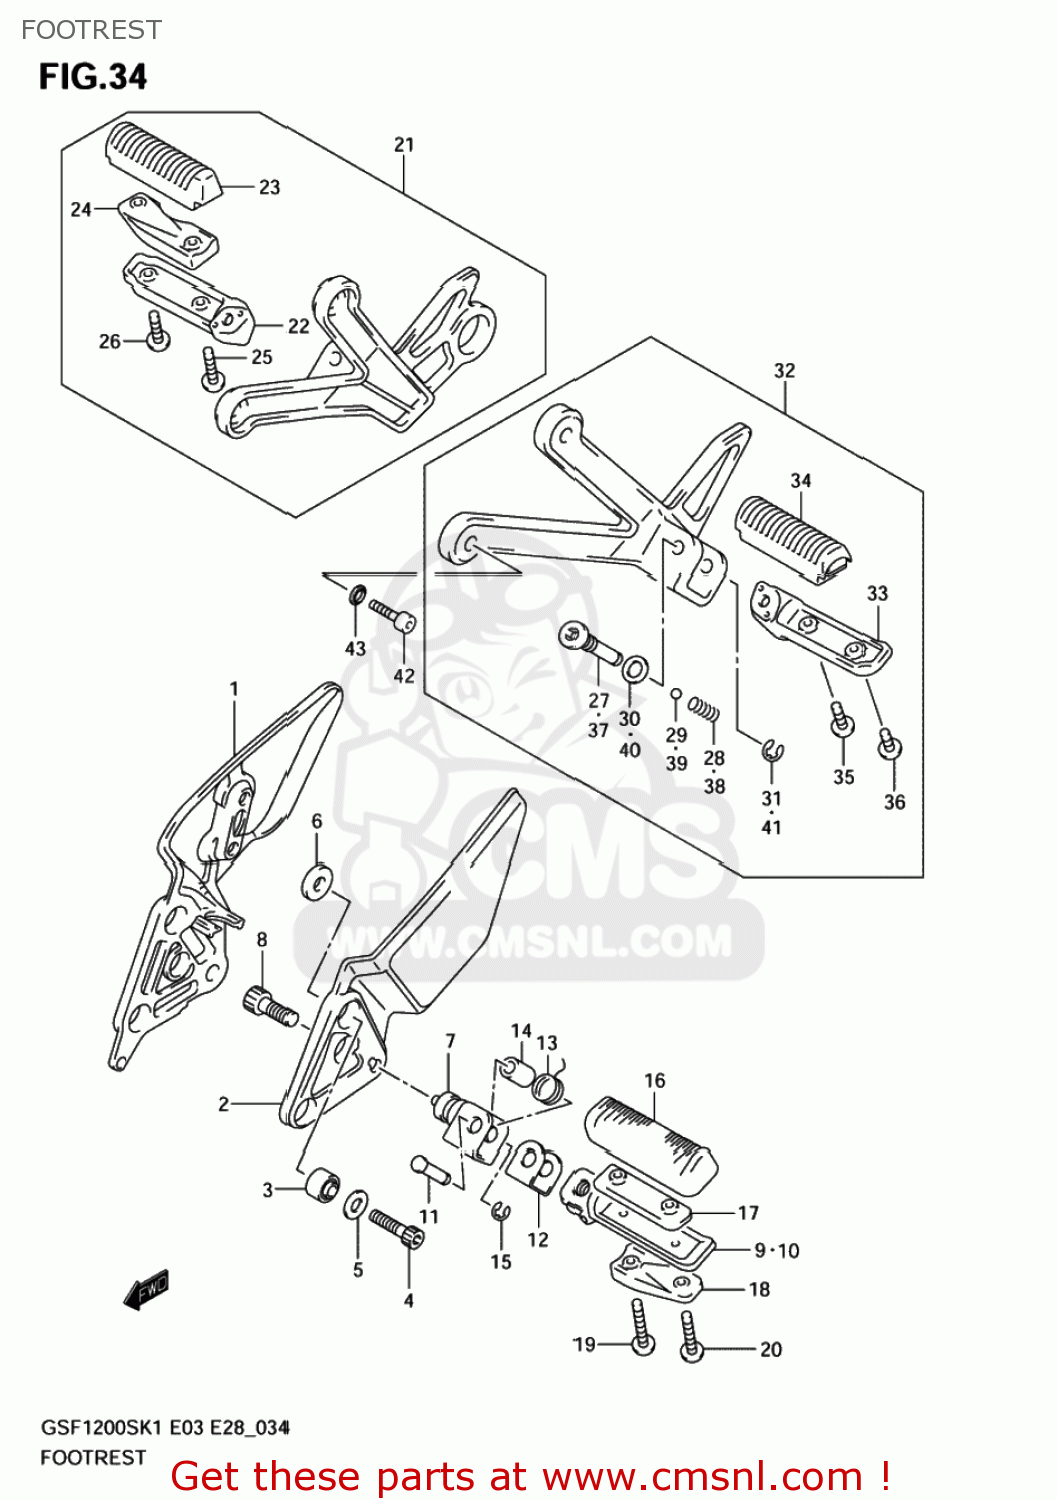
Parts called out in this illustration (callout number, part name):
1	BRACKET,FR FOOTREST,R
2	BRACKET,FR FOOTREST,L
3	BUSH(8.4X20X16)
4	BOLT(8X30)
5	WASHER(13.7X24X1.9)
6	WASHER(17.2X24X2.2)
7	HOLDER,FOOTREST
8	BOLT(10X28)
9	BAR,FOOTREST,R
10	BAR,FOOTREST,L
11	PIN(8X33.2)
12	CUSHION,FR FOOTREST
13	SPRING
14	SPACER(8.1X12X22)
15	E.RING
16	RUBBER,FOOTREST
17	BALANCER,FR FOOTREST UPR
18	BALANCER,FR FOOTREST LWR
19	SCREW
20	SCREW
21	FOOTREST ASSY,PILLION,R
22	BAR,PILLION FOOTREST,R
23	RUBBER,FOOTREST
24	BALANCER,PILLION LWR
25	SCREW
26	SCREW
27	BOLT,PILLION FOOTREST
28	SPRING
29	BALL
30	WASHER(10.5X24X1.6)
31	E.RING
32	FOOTREST ASSY,PILLION,L
33	BAR,PILLION FOOTREST,L
34	RUBBER,FOOTREST
35	SCREW 5X20
36	SCREW
37	BOLT,PILLION FOOTREST
38	SPRING
39	BALL
40	WASHER(10.5X24X1.6)
41	E.RING
42	BOLT(8X25)
43	WASHER
